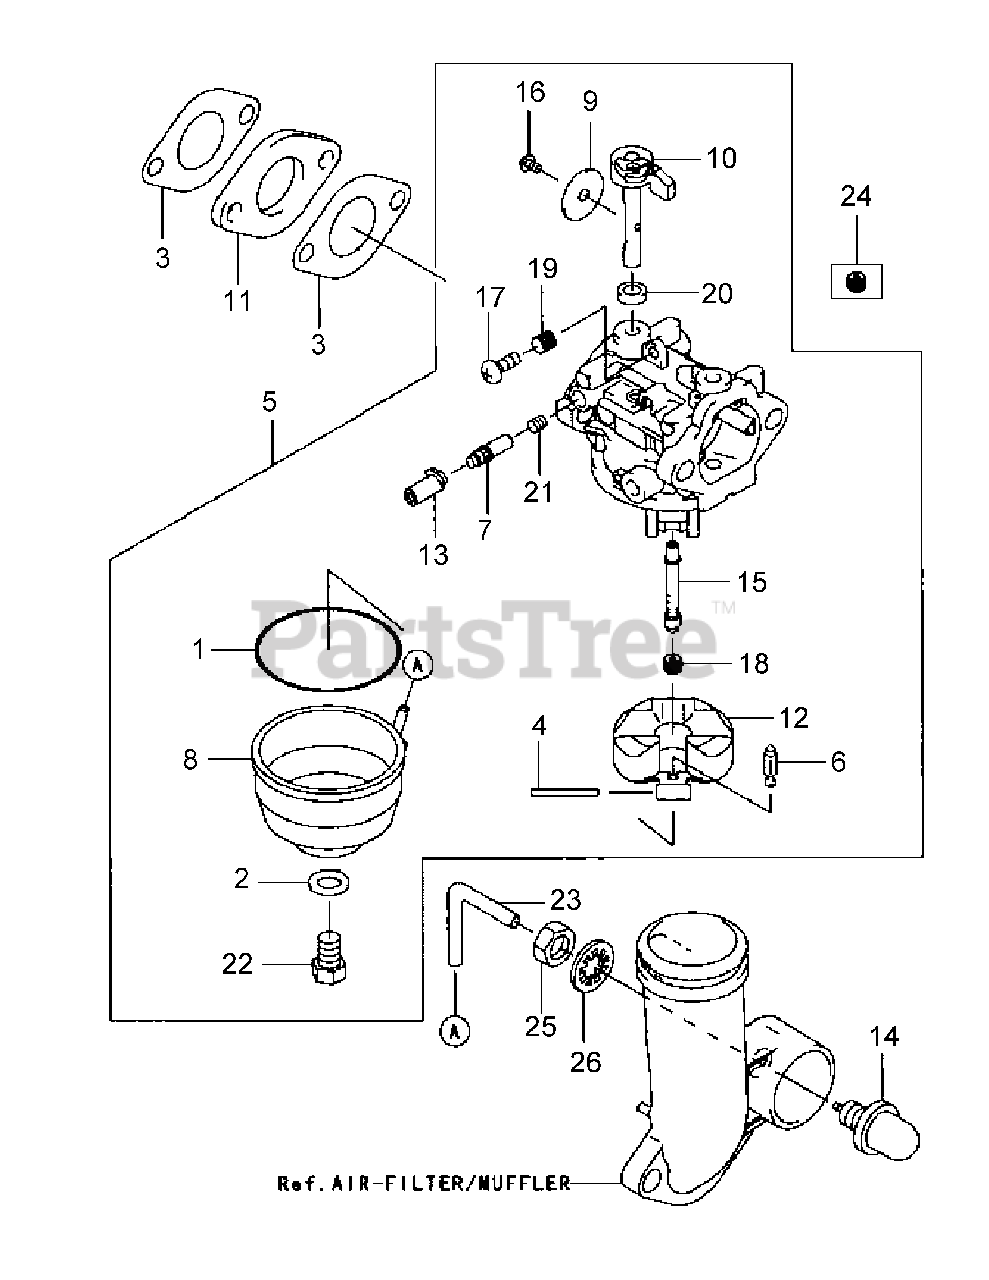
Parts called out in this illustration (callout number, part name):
3	Gasket
5	Carburetor Assy.
7	Pilot Air Screw
8	Float Chamber
9	Throttle Valve
10	Throttle Shaft
11	Insulator
18	Main Jet, #76
23	Tube, 2x5x65
25	Hex Nut, Fine
26	Toothed Washer
